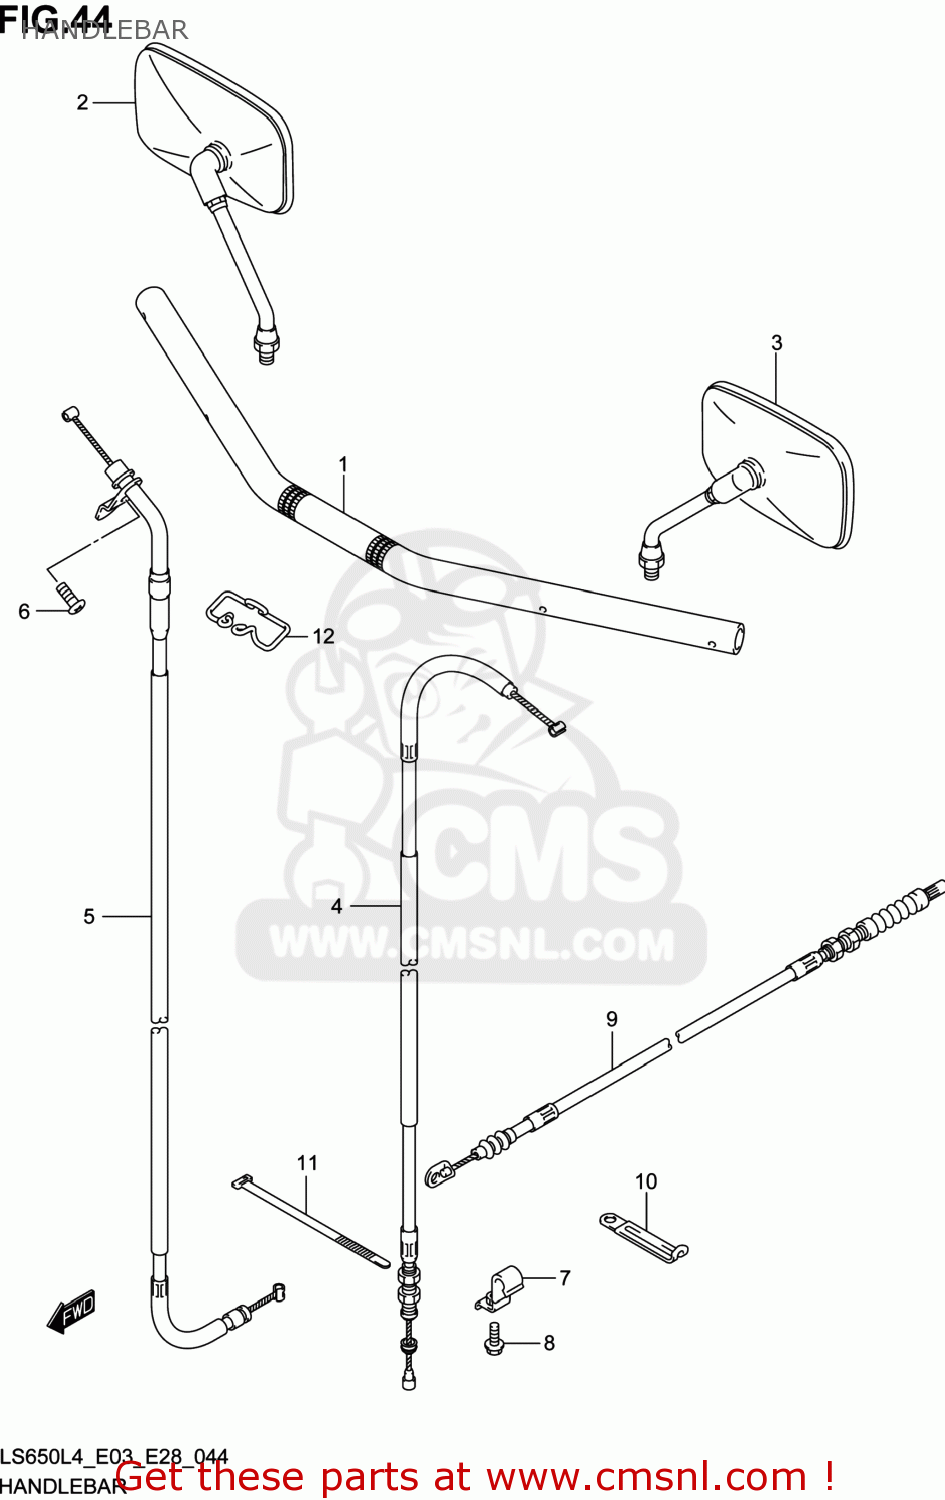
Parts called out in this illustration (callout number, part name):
1	HANDLEBAR
2	MIRROR ASSY,RR VIEW,R
3	MIRROR ASSY,RR VIEW,L
4	CABLE ASSY,CLUTCH
5	CABLE ASSY,THROTTLE
6	SCREW(5X10)
7	CLAMP,STOP LAMP SWITCH CABLE
8	BOLT
9	CABLE,STOP LAMP SWITCH
10	CLAMP(L:65)
11	CLAMP(L:145)
12	GUIDE,CABLE
